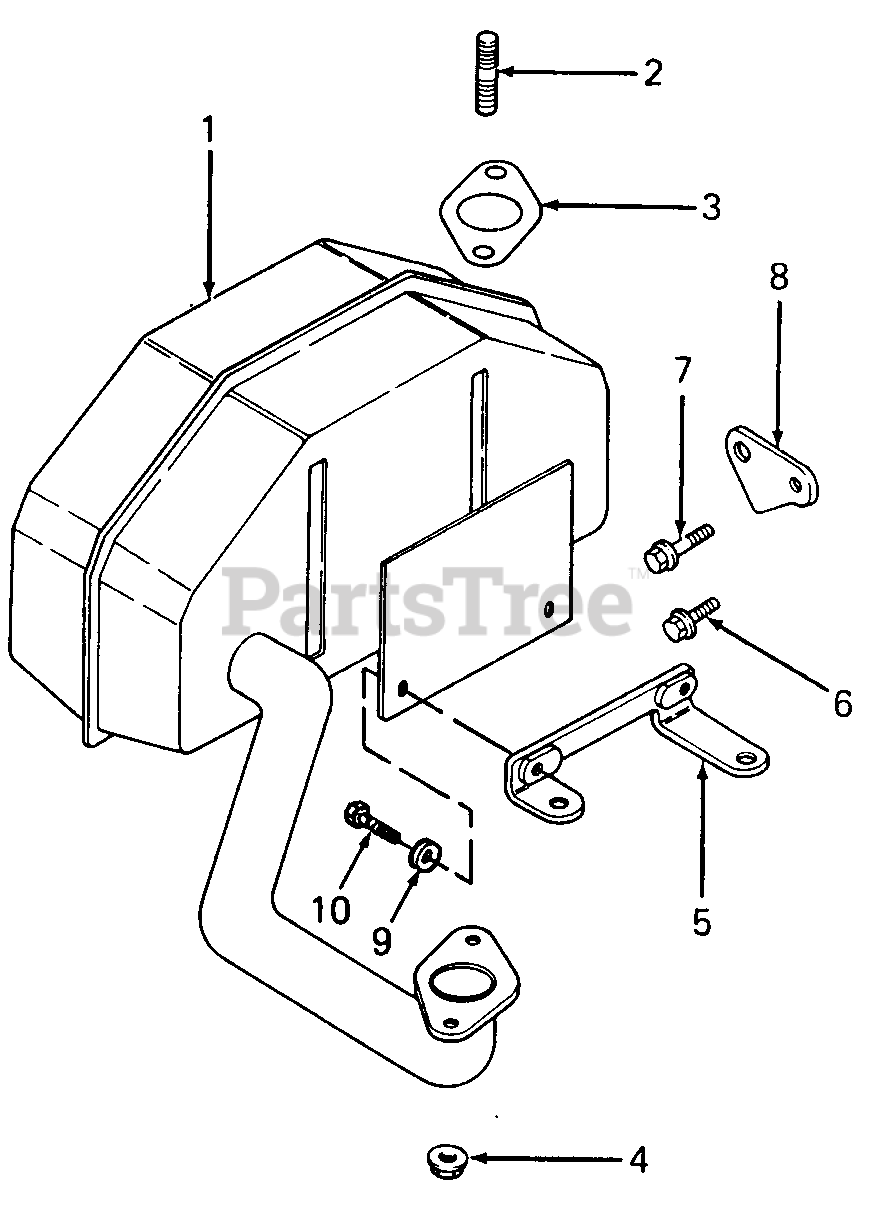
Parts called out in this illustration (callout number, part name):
2	Stud, Exhaust Manifold, M8 X 1.25 X 20
3	Gasket, Exhaust Manifold
4	Nut
5	Bracket, Muffler
6	Screw, Valve Cover, M6 X 1.0 X 20
7	Screw, Lifting Strap, M6 X 1.0 X 25
8	Strap, Lifting
9	Washer, Flat, .265 X 1.0 X .030 Thk HDN
10	Screw, Hex Cap, M6 X 1.0 X 10 mm Lg GR5
